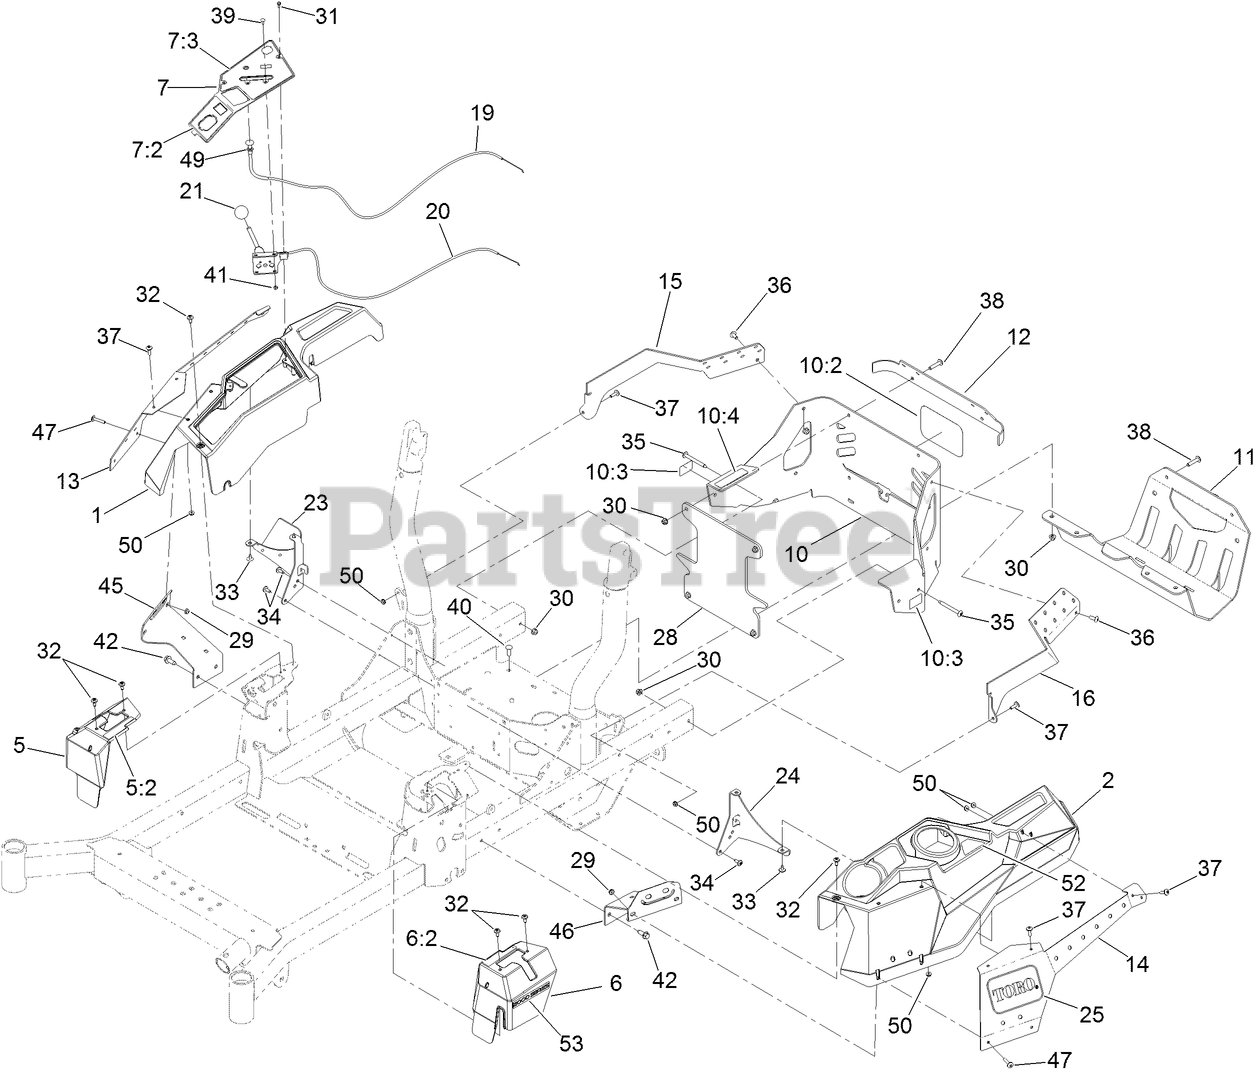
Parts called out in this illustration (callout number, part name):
1	CONSOLE-RH
2	CONSOLE-LH
5	COVER-CONTROL, MOTION (RH)
5:2	DECAL-CONTROL, MOTION (RH)
6	COVER-CONTROL, MOTION (LH)
6:2	DECAL-CONTROL, MOTION (LH)
7	CONTROL PANEL ASM
7:2	DECAL-PANEL, CONTROL
7:3	DECAL-PANEL, CONTROL
10	REAR GUARD ASM
10:2	DECAL
10:3	DECAL-WARNING
10:4	DECAL-ARRESTOR, SPARK
11	GUARD-MUFFLER
12	TRIM-UPPER, REAR
13	COVER,POD RH
14	COVER [BLACK]
15	BRACKET-GUARD, RH
16	BRACKET-GUARD, LH
19	CABLE-CONTROL, CHOKE
20	CABLE-CONTROL, THROTTLE
21	KNOB-BALL
23	SUPPORT-CONSOLE, RH
24	BRACKET-CONSOLE, LH
25	DECAL
28	WEIGHT-REAR [RED]
29	NUT-HF
30	NUT-HF, NI
31	SCREW-HWH
32	SCREW-SHOULDER
33	SCREW-TORX
34	SCREW-TORX
35	SCREW-TORX
36	SCREW-TORX
37	SCREW-TRUSS
38	SCREW-TORX
39	BOLT-CARR
40	SCREW-CARR
41	NUT-LOCK, NI
42	SCREW-FORMING, THREAD
45	BRACKET-SUPPORT, POD (RH)
46	BRACKET-SUPPORT, POD (LH)
47	SCREW-TRUSS
49	NUT-HJ
50	NUT-KEPS
52	DECAL-FILL, FUEL
